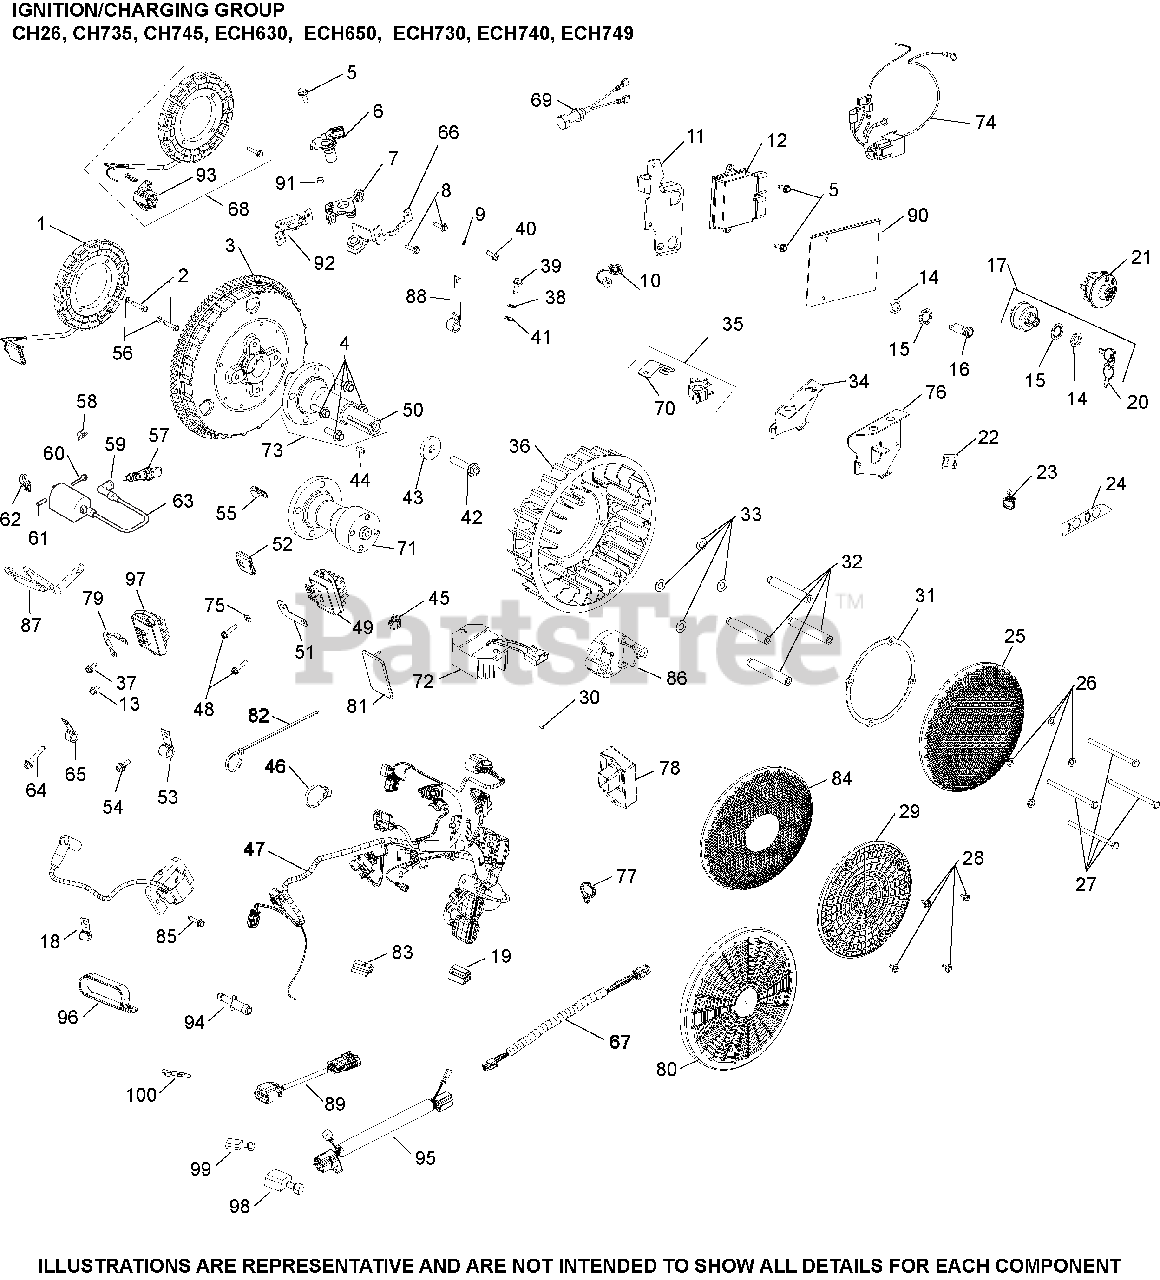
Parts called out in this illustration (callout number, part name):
2	SCREW, THREAD FORMING
3	FLYWHEEL, ASSEMBLY
6	SENSOR, SPEED
8	SCREW, THREAD FORMING
9	WASHER, INT TOOTH LOCK #10
10	CAP, CONNECTOR
11	BRACKET, ECU
12	MODULE, ECU
14	NUT, KEY SWITCH
15	WASHER, INTERNAL TOOTH
16	LIGHT, INDICATOR
17	KEY SWITCH ASSEMBLY
17	SWITCH, KEY ASSEMBLY USE 25 099 37-S
25	KIT, GRASS SCREEN
28	SCREW, FLG SEMS M4X.7X25
30	SCREW, FLG M10X1.5X45 - (#25086361S)
35	KIT, MOUNTING CLIP
36	FAN USE 24 755 253-S
37	SCREW, THREAD FORMING
38	WASHER, INT TOOTH LOCK 1/4"
41	WASHER, FLAT 1/4" (O.D. 1/2")
43	WASHER, FLAT 13/32"
44	KEY, 3/16" X 5/8"
47	HARNESS, WIRING ASSEMBLY
48	SCREW, HEX FLANGE HI-LO
52	CONNECTOR
54	BOLT, SHOULDER
57	PLUG, SPARK (PRO SERIES)
62	CLIP, SNAP-IN
63	COIL, IGNITION - EFI
64	SCREW, FLG M6X1.0X34
68	KIT, 25 AMP STATOR ASSY.
70	CLIP, MOUNTING BRACKET USE 25 154 21-S
80	SCREEN, GRASS
92	BRACKET, SENSOR
97	REGULATOR, RECTIFIER (20-30AMP,FW W/O USE 25 403 39-S
